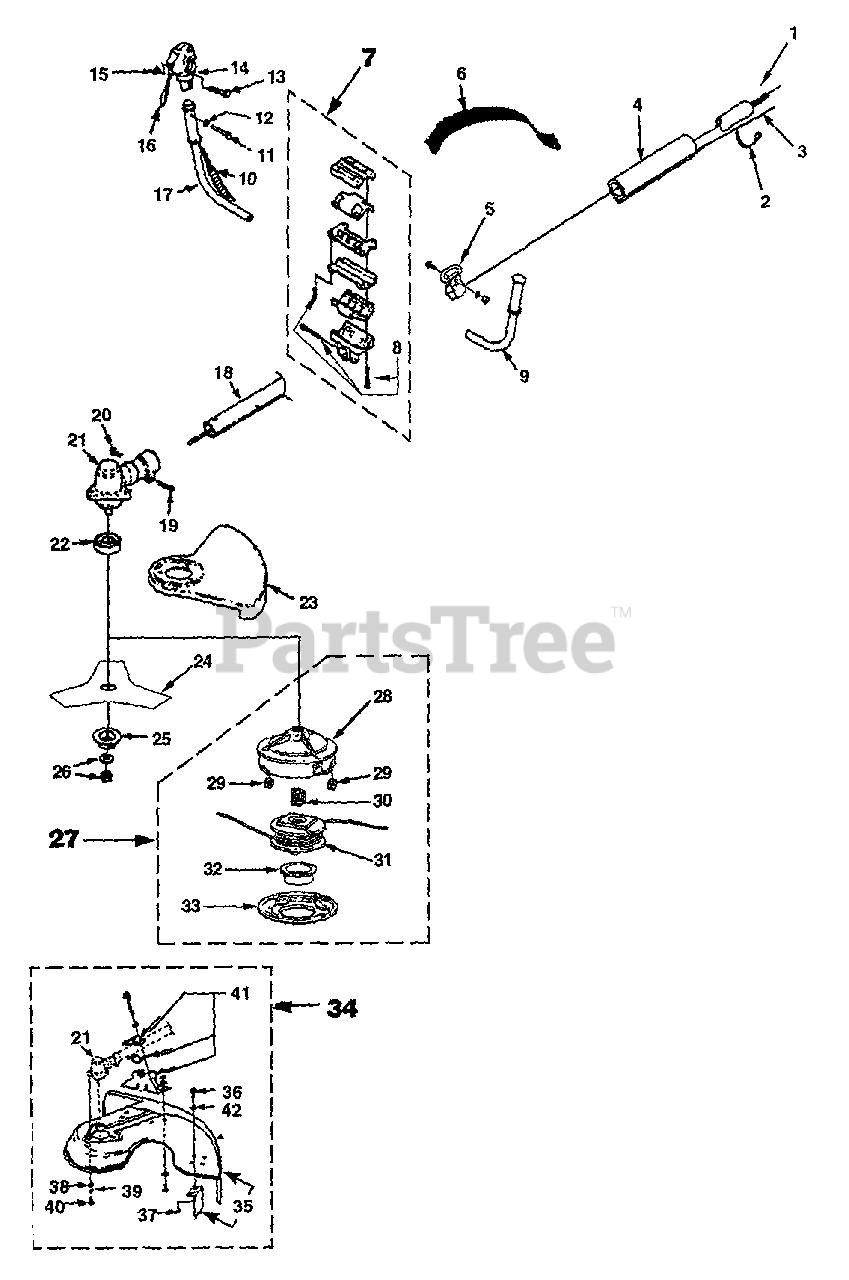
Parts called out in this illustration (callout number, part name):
1	DRIVE SHAFT
2	CABLE-Tie
3	THROTTLE CABLE
4	HIP PAD
5	BRACKET-Hanger
6	SHOULDER HARNESS (Full)
7	HANDLE BAR BRACKET
9	HANDLE BAR & GRIP (Left)
10	SLEEVING
11	SCREW-Thread Form (#6-19 X 3/4")
12	WASHER-Lock (#8)
13	SCREW-(m4 X 25)
14	SWITCH & LEAD
15	NUT-Hex (M4)
16	THROTTLE
17	HANDLE BAR & GRIP (Right)
18	DRIVE SHAFT HOUSING
19	SCREW-Cap Socket Hd. (1/4-20 X 7/8")
20	SCREW-Sems Hex Hd.
21	GEAR HEAD
22	WASHER-Flanged
23	GUARD-Blade
24	BLADE-Tri-Arc
25	WASHER-Cupped
26	NUT-Lock
27	STRING HEAD
28	HOUSING, String
29	EYELET
31	SPOOL W/String
32	BUTTON
34	GRASS DEFLECTOR KIT
35	DEFLECTOR & BLADE
36	SCREW-Mach. Hex Hd. (10-24 X 7/8")
37	NUT-Hex Locking (10-24)
38	WASHER-Flat (#10)
39	WASHER-Lock (#10)
40	SCREW-Hex Hd. (10-24 X 5/8")
41	DEFLECTOR BRACKET KIT
